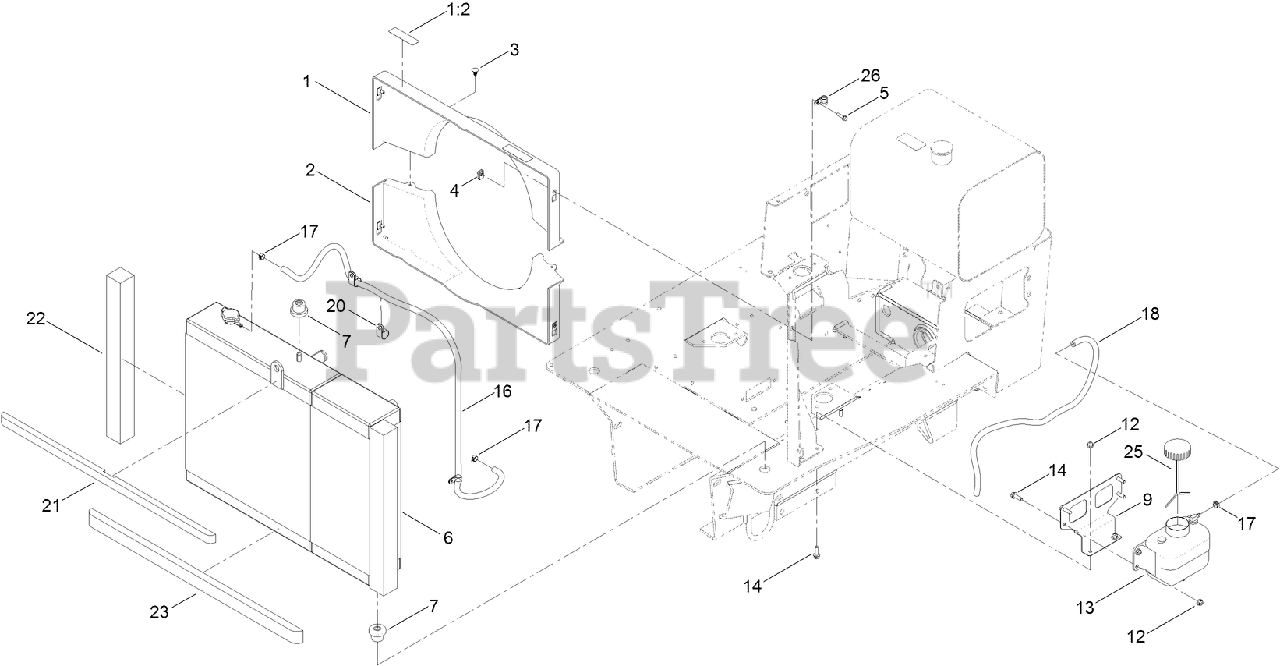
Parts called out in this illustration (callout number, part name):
1	FAN SHROUD ASM
1:2	DECAL-WARNING
2	SHROUD-BOTTOM
3	PLUG-PLASTIC
5	SCREW-HHF
6	COOLING ASM
7	MOUNT-ISOLATOR
9	BRACKET-TANK
12	NUT-HF, NI
13	TANK-RECOVERY, COOLANT
14	SCREW-HHF
16	HOSE-FUEL
17	CLAMP-HOSE
18	HOSE-FUEL
20	CLAMP-R
21	SEAL-FOAM
22	SEAL-FOAM
23	SEAL-FOAM
25	CAP-RESERVOIR
26	CLAMP-R
